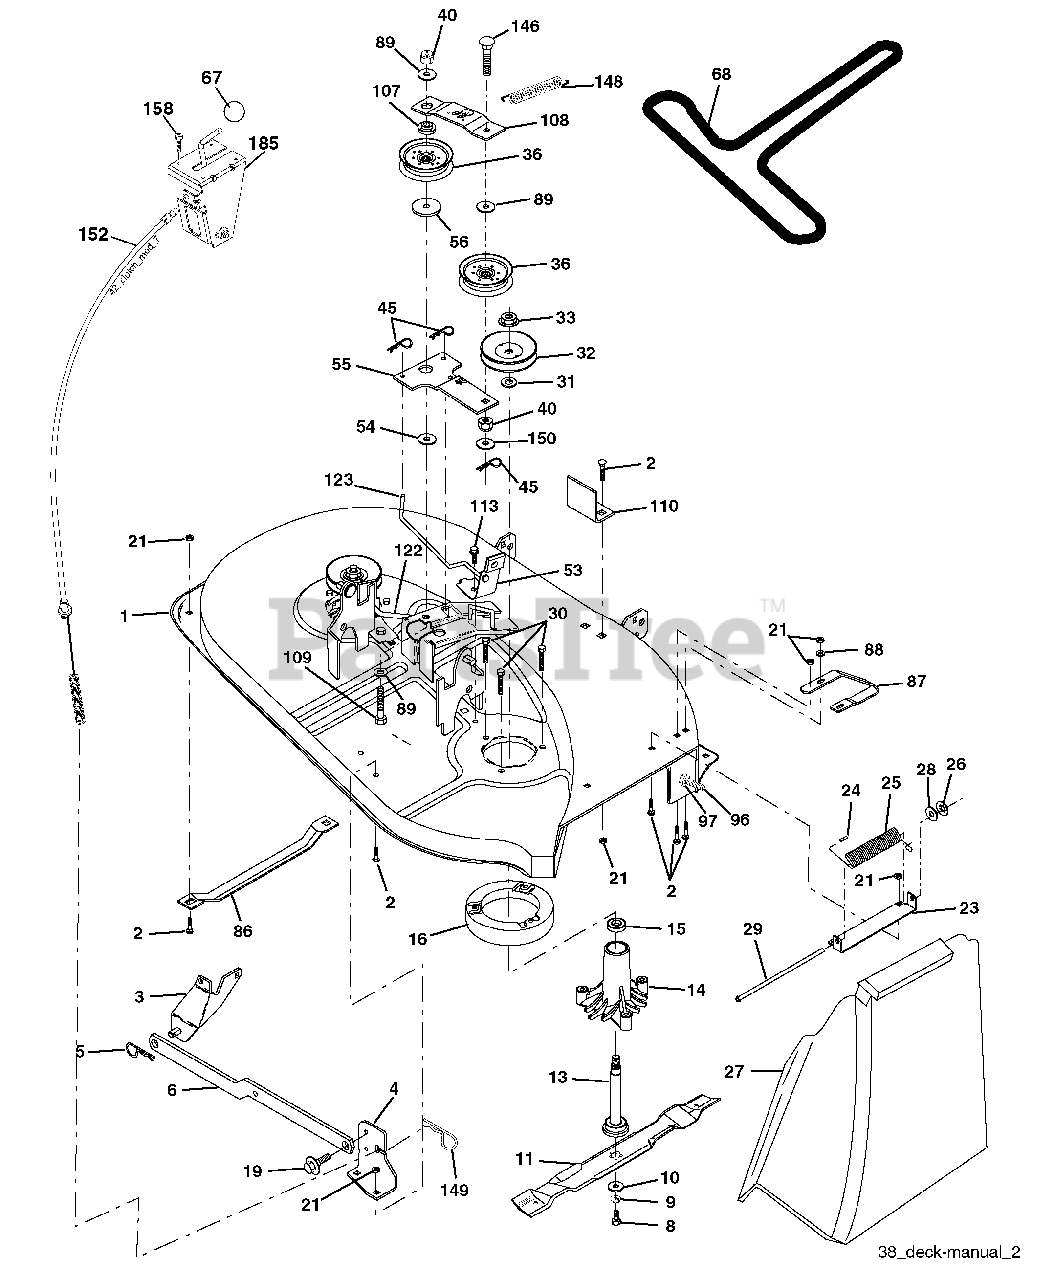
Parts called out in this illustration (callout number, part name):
1	Mower Housing Assembly
2	Bolt Carriage 5/16-18 x 3/4
3	Bracket Asm Fr. Sway Bar
4	Bracket Deck Sway Bar 38"/42"
5	Retainer Spring
6	Bar Sway Deck
8	Bolt 3/8-24 x 1.25 Gr. 8
11	Blade Mower
13	Shaft Assembly, Mandrel, Vented
14	Housing, Mandrel, Vented
15	Bearing, Ball, Mandrel
18	Blade Rdhd Sqnk 5/16-18 x 5/8
19	Bolt, Shoulder
20	Baffl e Vortex Front
21	Nut
23	Bracket, Mower Defl ector
24	Cap, Sleeve
25	Spring, Torsion, Defl ector
26	Nut, Push
27	Shield, Defl ector
29	Rod, Hinge
30	Screw Thdrol.
31	Washer, Spacer
32	Pulley, Mandrel
33	Nut, Toplock
36	Pulley, Idler, Flat
37	Pulley, Idler Flat
40	Nut, Crownlock 3/8-16 unc
45	Retainer
53	Brake Assembly
55	Idler Arm Assembly
56	Spacer, Retainer
67	Knob
68	V-Belt
72	Spring Brake Return
89	Washer 13/32 x 13/16 x 11 Ga.
107	Spacer Retainer
108	Stiffener, Idler Arm
122	Rod, Brake LH
123	Rod, Brake RH
144	Keeper Belt Idler Tension
148	Spring Return Idler
149	Retainer Spring Yellow
150	Washer 9/32 x 3/4 x 10 Ga.
152	Clutch Cable 38"
158	Screw Hex Thd Cut 1/4-20 x 1/2
185	Head Asm Cable Clutch
186	Screw Hex Wsh Thdrol 3/8-16 x 2-3/4
187	Keeper Belt M Shape
188	Bolt Carriage Idler
189	Brake Stand
190	Brake Arm
191	Brake Spacer
192	Brake Assembly
193	Keeper Belt Rh Mandrel
194	Brake Guard
195	Washer 13/32 x 2 x 10 Ga.
195	Mandrel Assembly
195	Replacement Mower, Complete
